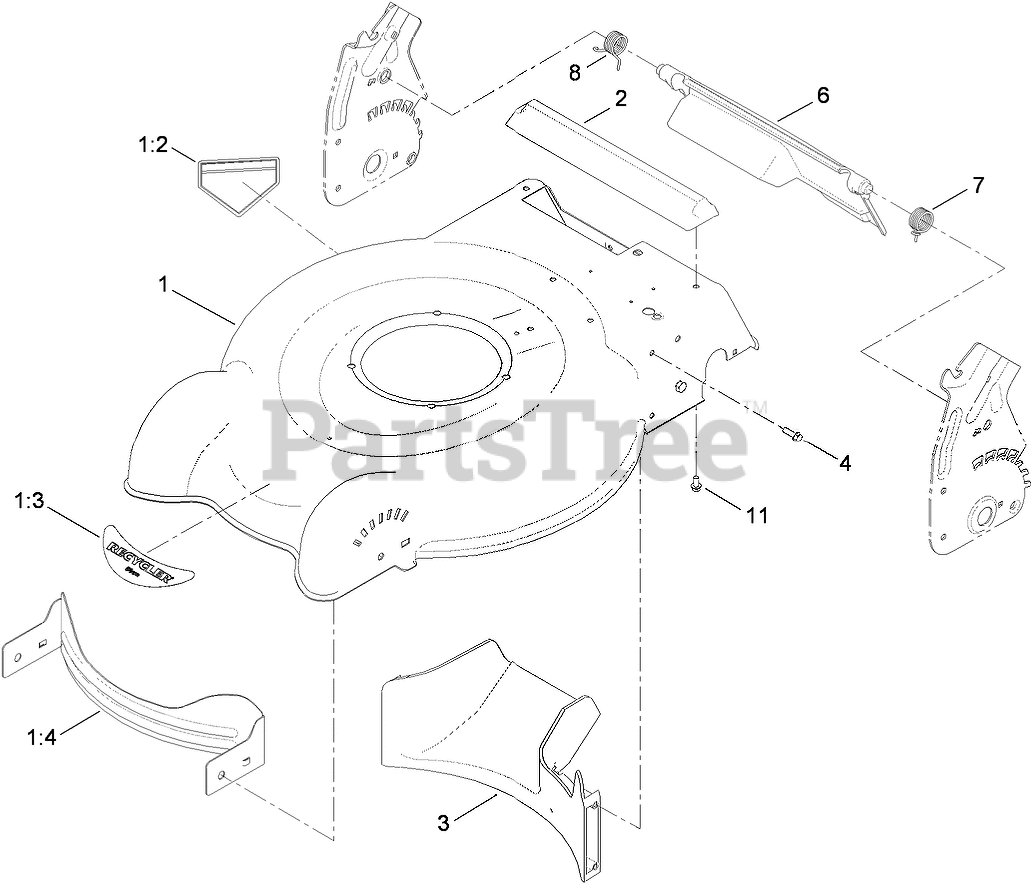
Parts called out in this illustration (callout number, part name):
1	HOUSING ASM
1:2	DECAL-DANGER
1:3	DECAL-DECK
1:4	BAFFLE-FRONT
2	CHUTE-REAR
3	BAFFLE-REAR
4	SCREW-HWH
6	REAR DEFLECTOR ASM
7	SPRING-TORSION, LH
8	SPRING-TORSION, RH
11	SCREW-PLASTITE
